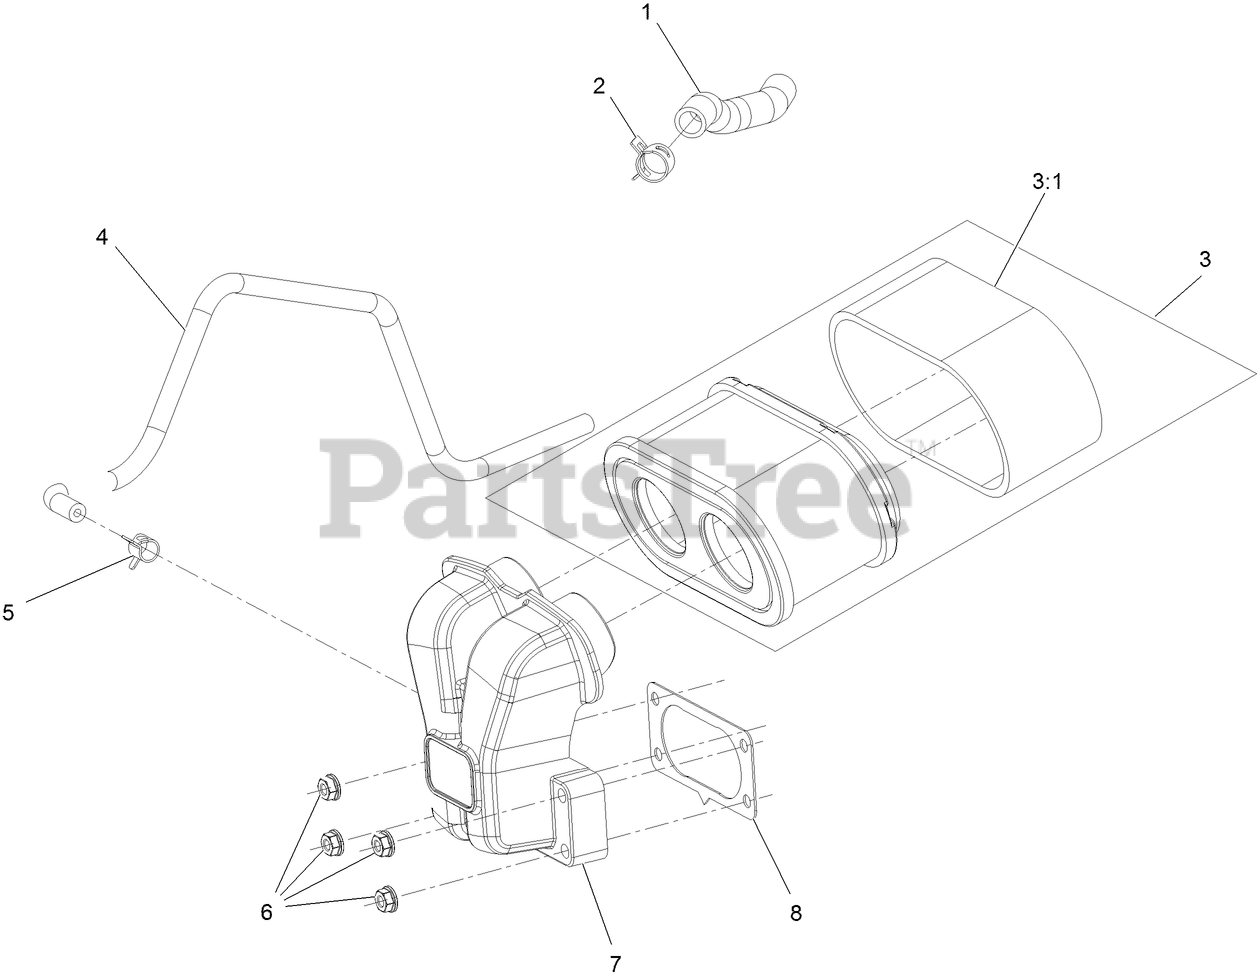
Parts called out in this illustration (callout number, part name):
1	TUBE-BREATHER
2	CLAMP-HOSE
3	AIR FILTER KIT
3:1	PREFILTER
4	HOSE-FUEL
5	CLAMP-HOSE
6	NUT-FLANGE
7	MANIFOLD-FILTER, AIR
8	GASKET-CARBURETOR
